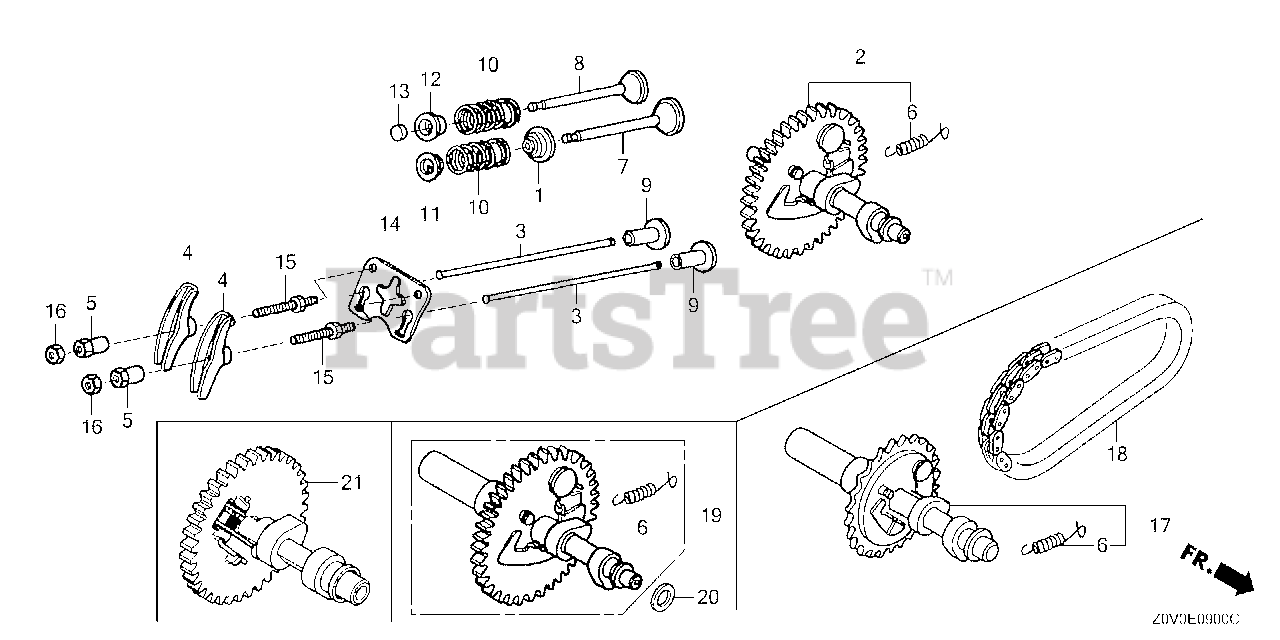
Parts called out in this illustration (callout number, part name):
1	SEAL, VALVE STEM
2	CAMSHAFT ASSY.
4	ARM, VALVE ROCKER
5	PIVOT, ROCKER ARM
6	SPRING, WEIGHT RETURN
7	VALVE, IN.
8	VALVE, EX. (STELLITE)
9	LIFTER, VALVE
10	SPRING, VALVE
11	RETAINER, IN. VALVE SPRING
11	RETAINER, VALVE SPRING
12	RETAINER, EX. VALVE SPRING
13	ROTATOR, VALVE
14	PLATE, PUSH ROD GUIDE
15	BOLT, PIVOT (8MM)
16	NUT, PIVOT ADJUSTING
